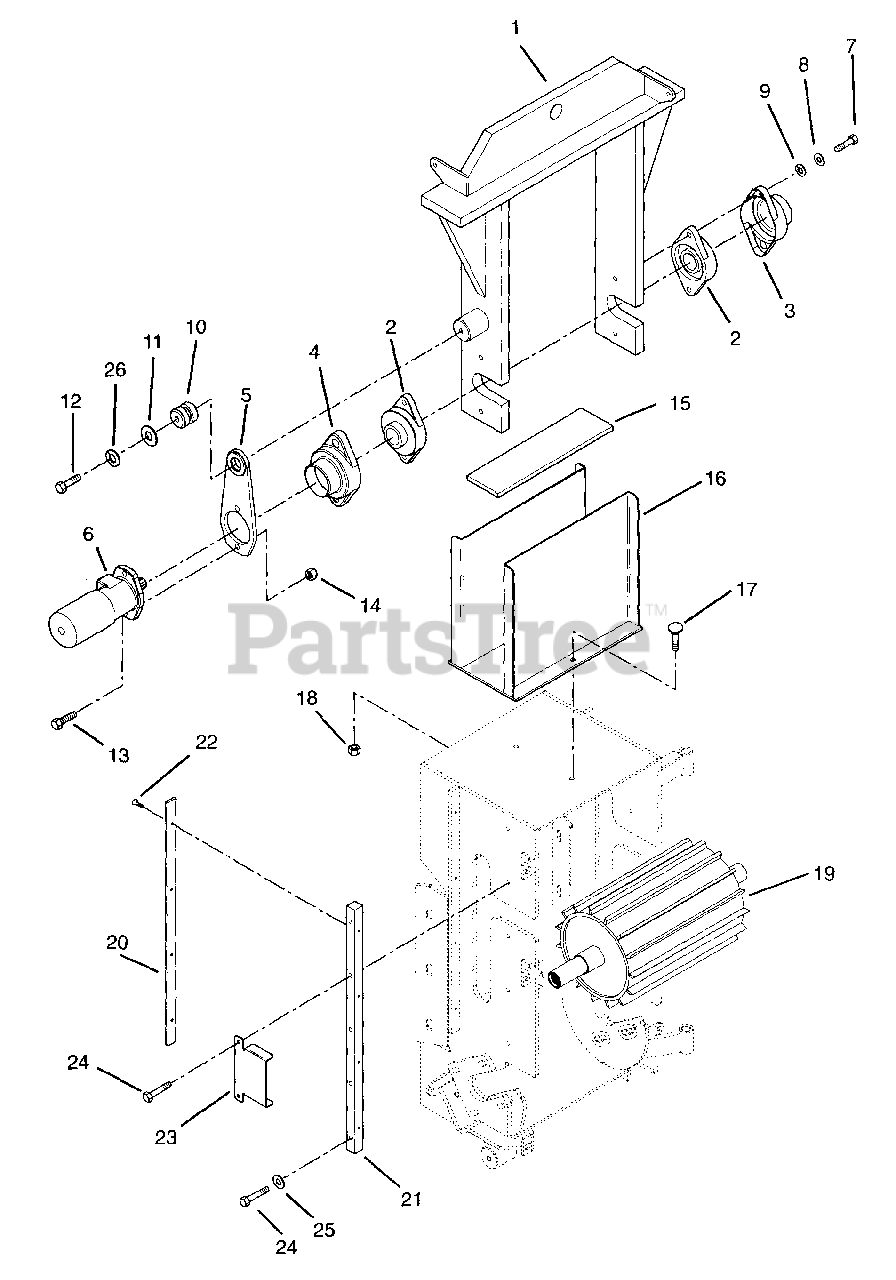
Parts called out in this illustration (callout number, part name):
1	Saddle Replacement
1	Saddle Weldment Assembly
3	Cover-Bearing
4	Cover-Shaft
5	Torque Arm Weldment
6	Hydraulic Motor
7	Bolt-Hex .50-13 x 1.25 Grade 5
8	Washer-Flat-Steel .531 x 1.06 x .095
9	Washer-Lock .50 x .125
10	Rubber Bushing
10	Bushing-Isolation
11	Washer-Flat-Steel .50 x 2.25 x .13
11	Washer-Flat-Steel .656 x 2.52 x .184
12	Bolt-Hex .50-13 x 3.00 Grade 5
12	Bolt-Hex .625-11 x 4.00 Grade 8
13	Bolt-Hex .50-13 x 1.50 Grade 5
14	Nut-Locking-Center .50-13
15	Rubber Stop
16	Saddle Guard Weldment
17	Bolt-Round Head Square Neck .38-16 x 1.00
18	Nut-Lock-Center .38-16
19	Roller-Top Weldment
20	Wear Strip
21	Front Guide
22	Screw-Machine .25-20 x.50
23	Feed Box Guard
24	Bolt-Hex .38-16 x 1.50 Grade 5
25	Washer-Flat-Steel .438 x 1.00 x .083
26	Washer-Locking .50 x .125
26	Washer-Locking .62 x .156
